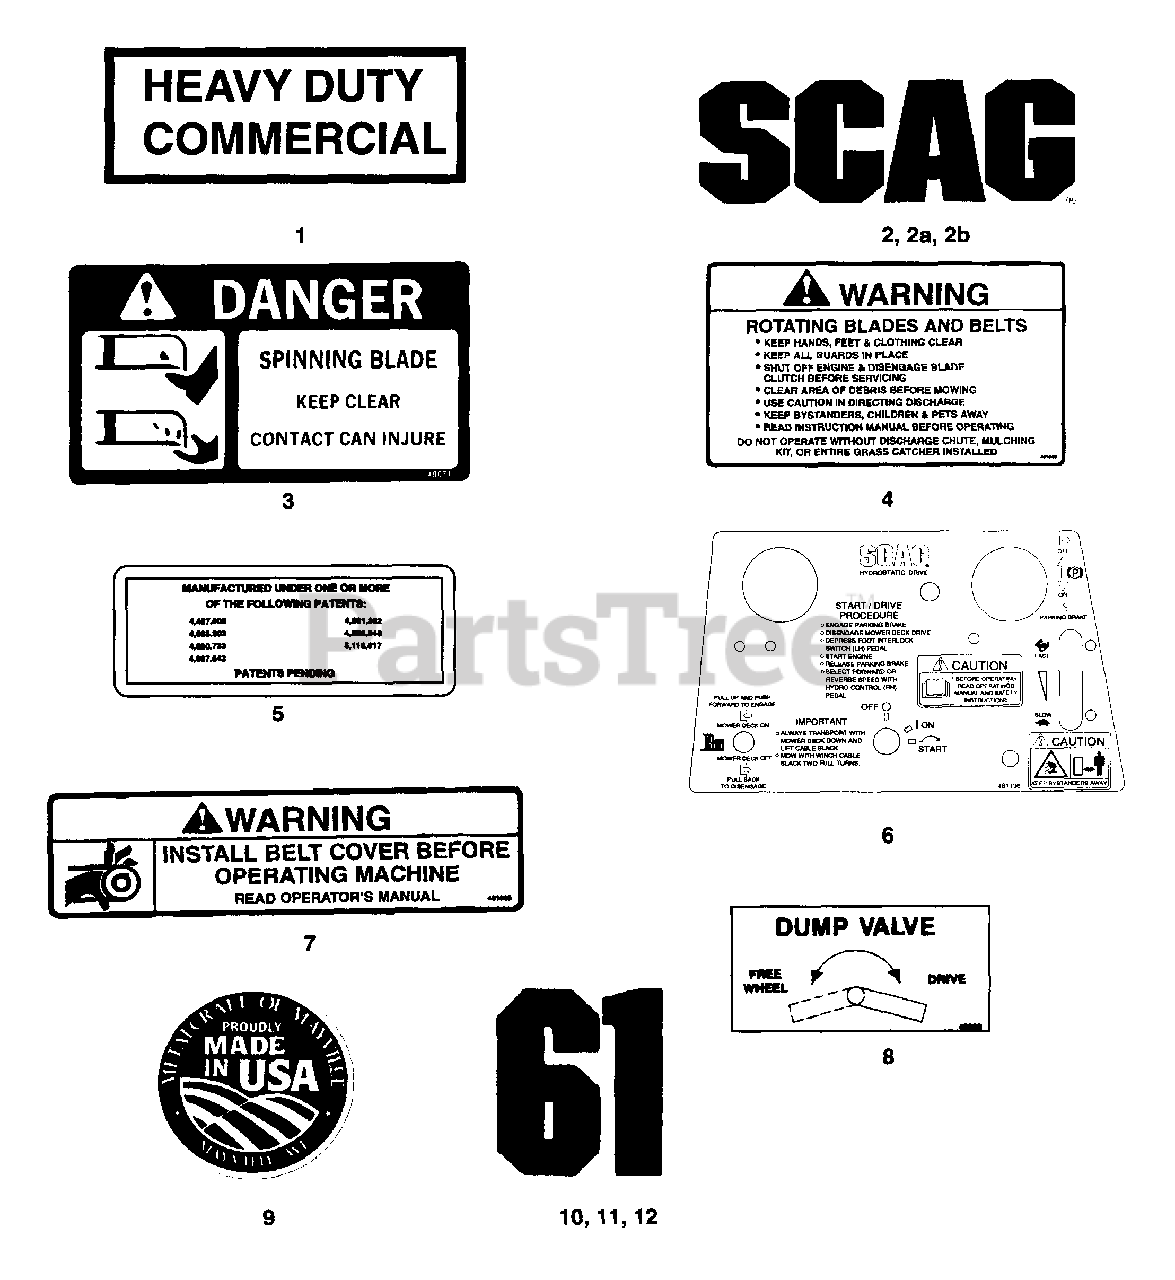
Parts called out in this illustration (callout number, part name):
1	Decal, Heavy Duty Commercial
2	Decal, Scag Logo
2A	Decal, Scag Logo
2B	Decal, Scag Logo Seatback
3	Decal, Danger-Spinning Blades
4	Decal, Warning-Rotating Blades
5	Decal, Patent
6	Decal, Instrument Panel
7	Decal, Warning-Belt Cover
8	Decal, Dump Valve
9	Decal, Metalcraft-Made In USA
10	Decal, 52
11	Decal, 61
12	Decal, 72
